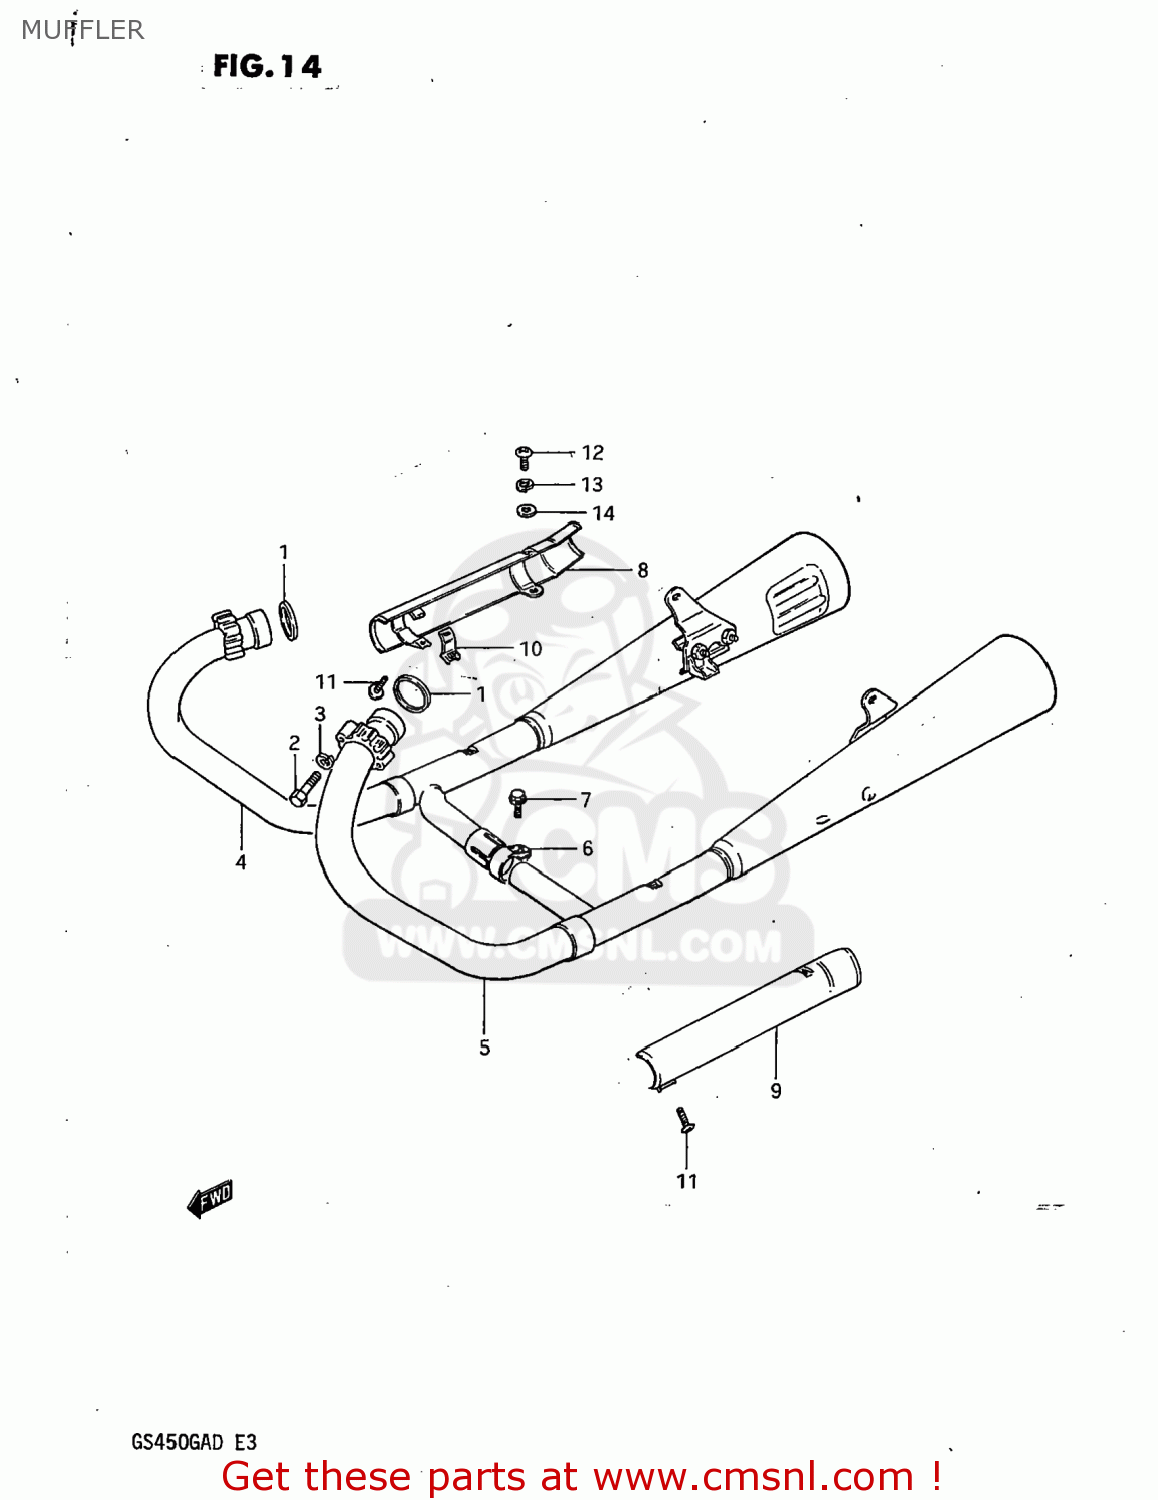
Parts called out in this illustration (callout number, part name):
1	GASKET,EXHAUST PIPE (NAS)
2	BOLT 8X40
3	LOCK WASHER
4	MUFFLER ASSEMBLY,RIGHT
5	MUFFLER ASSEMBLY,LEFT
6	CLAMP
7	BOLT
8	COVER,MUFFLER,RIGHT
9	COVER,MUFFLER
10	CLAMP,MUFFLER COVER
11	SCREW
12	SCREW
13	LOCK WASHER
14	WASHER
